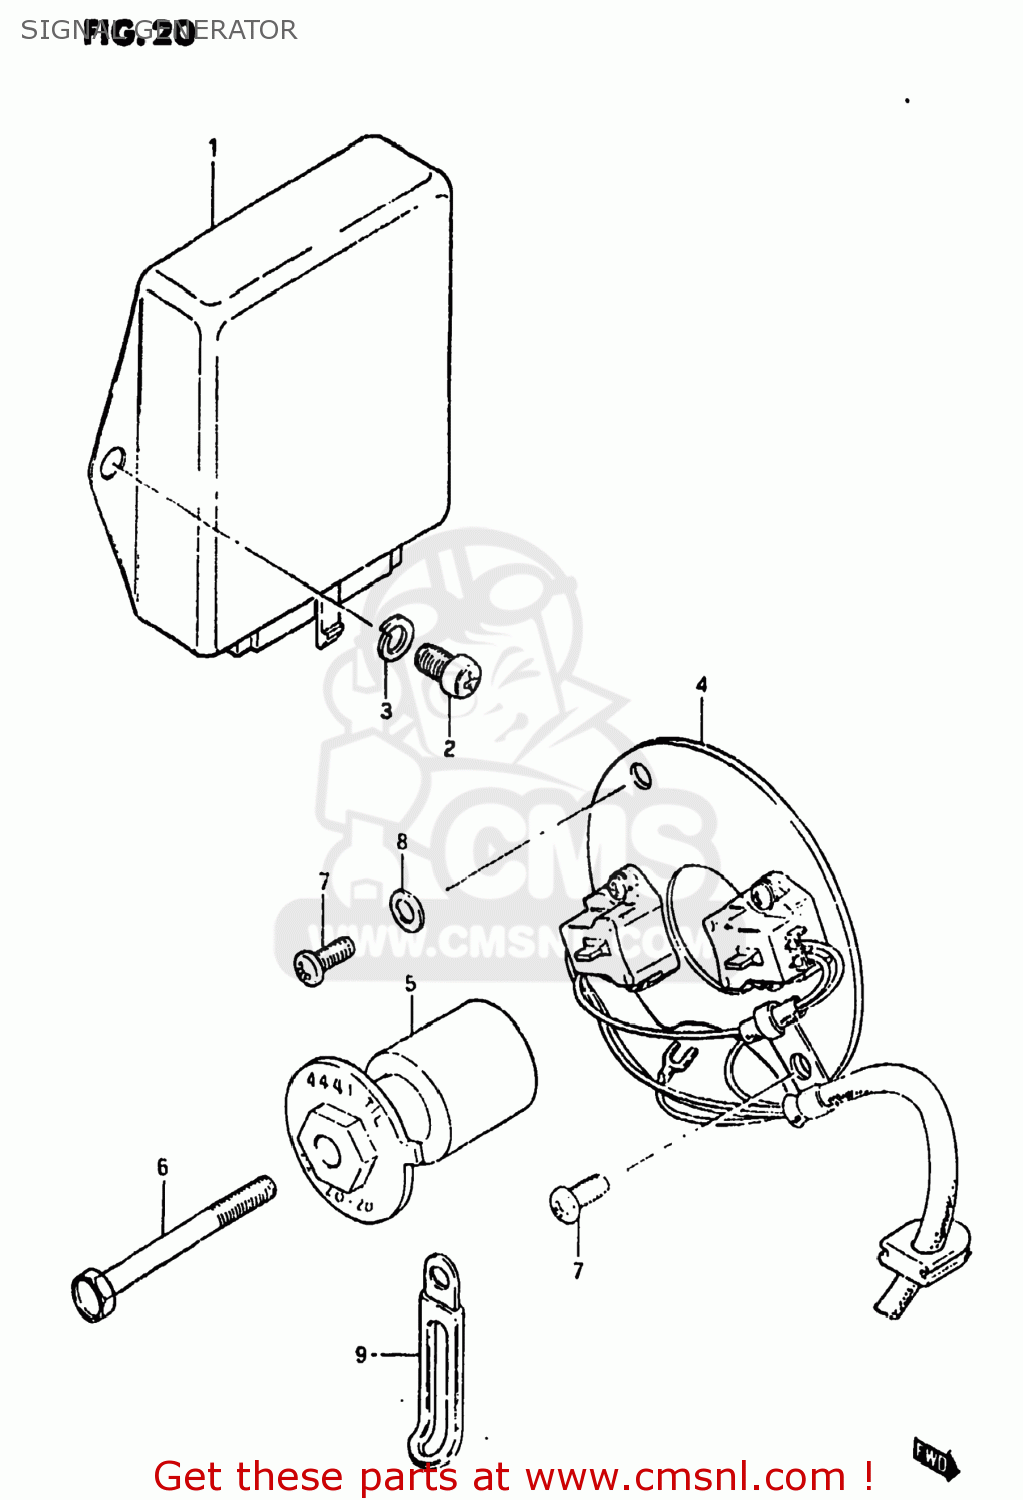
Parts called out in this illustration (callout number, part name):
1	IGNITOR UNIT
2	SCREW
3	LOCK WASHER
4	SIGNAL GENERATOR ASSEMBLY
5	ROTOR,SIGNAL
6	BOLT 6X60
7	SCREW(5X12)
8	WASHER
9	CLAMP L:35
